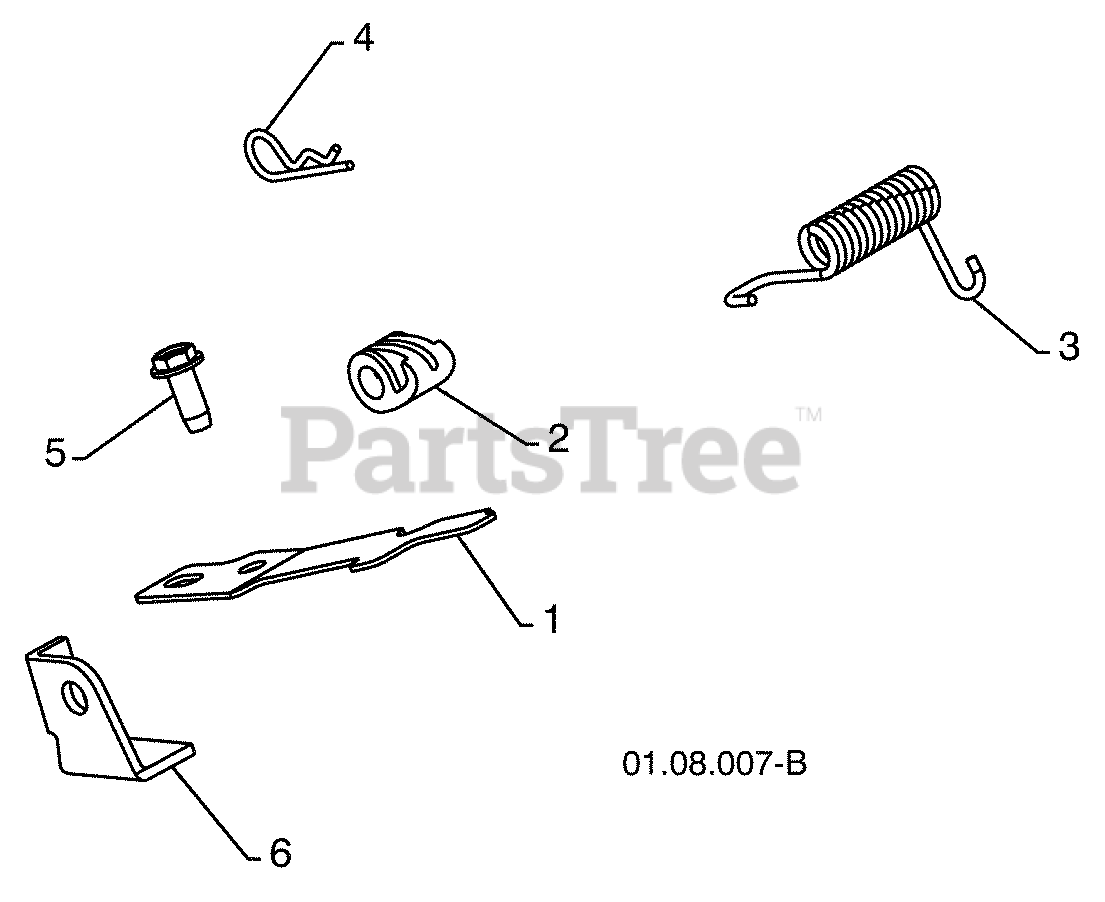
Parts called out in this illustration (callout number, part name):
1	INTERLOCK SPRING
2	INTERLOCK CAM
3	TORSION SPRING
5	SCREW 1/4--20 X .625
6	INTERLOCK STOP
